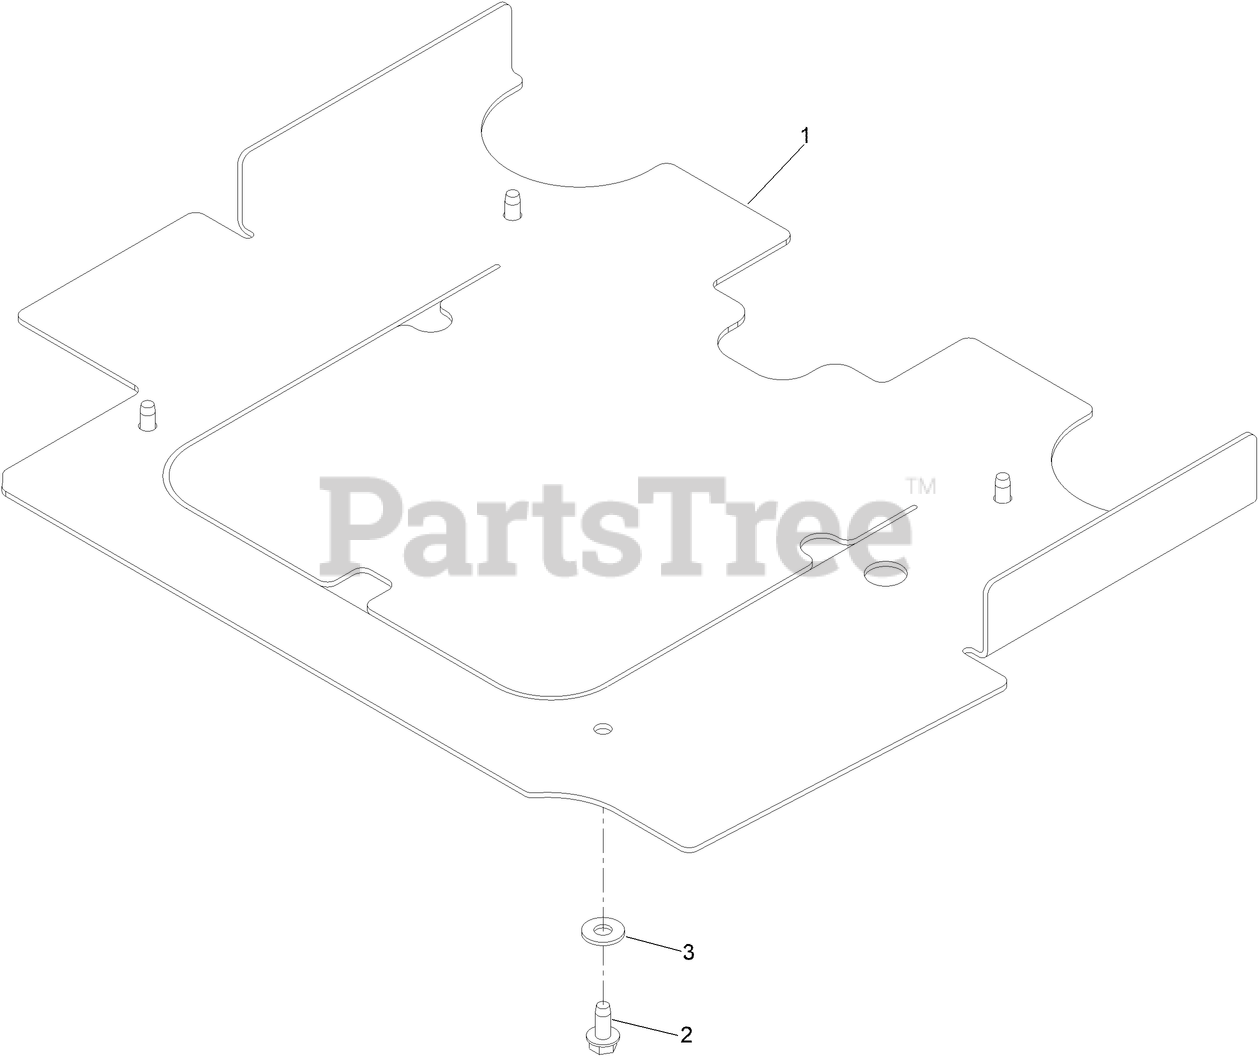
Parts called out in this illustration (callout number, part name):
1	SHIELD-HEAT
2	SCREW-HWHTF
3	WASHER-FLAT
